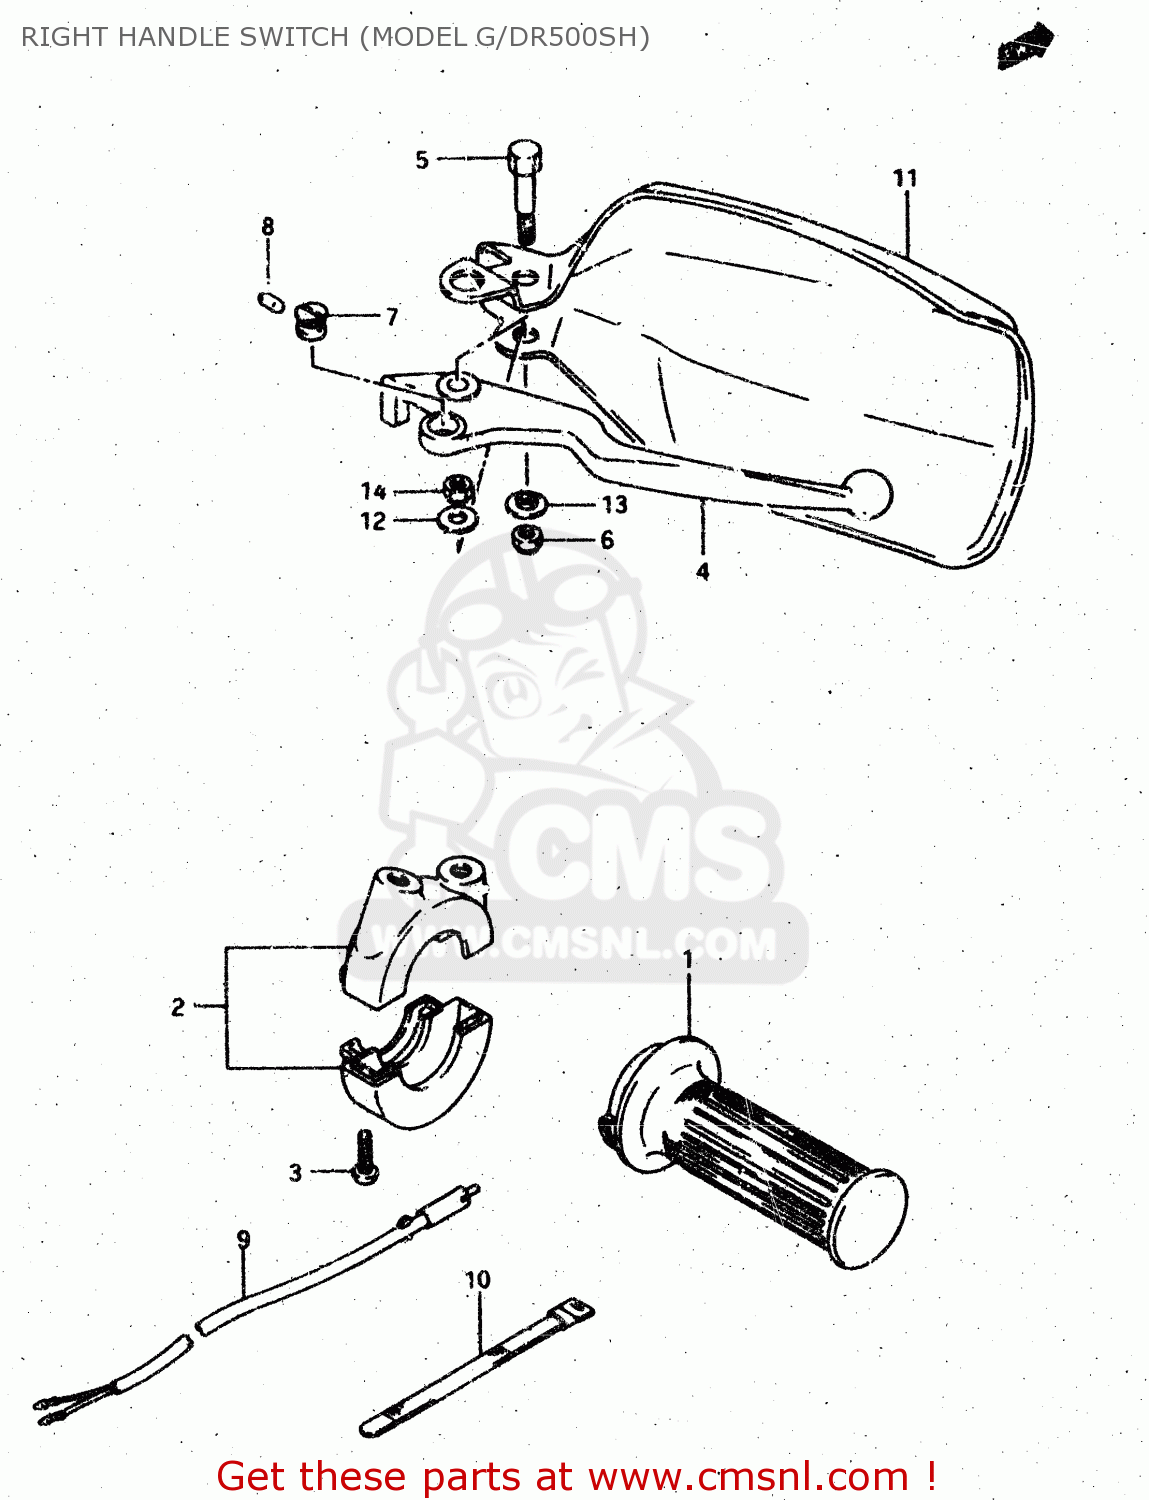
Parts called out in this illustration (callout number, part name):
1	GRIP,THROTTLE
2	CASE ASSY,THROTTLE
3	SCREW 5X20
4	LEVER,BRAKE
5	BOLT,LEVER PIVOT
6	NUT
7	ADJUSTER
8	ROD,PUSH
9	SWITCH ASSY,STOP
10	CLAMP(L:120)
11	COVER,KNUCKLE,R
12	WASHER(6.5X16X1.2)
13	WASHER
14	NUT 6MM
